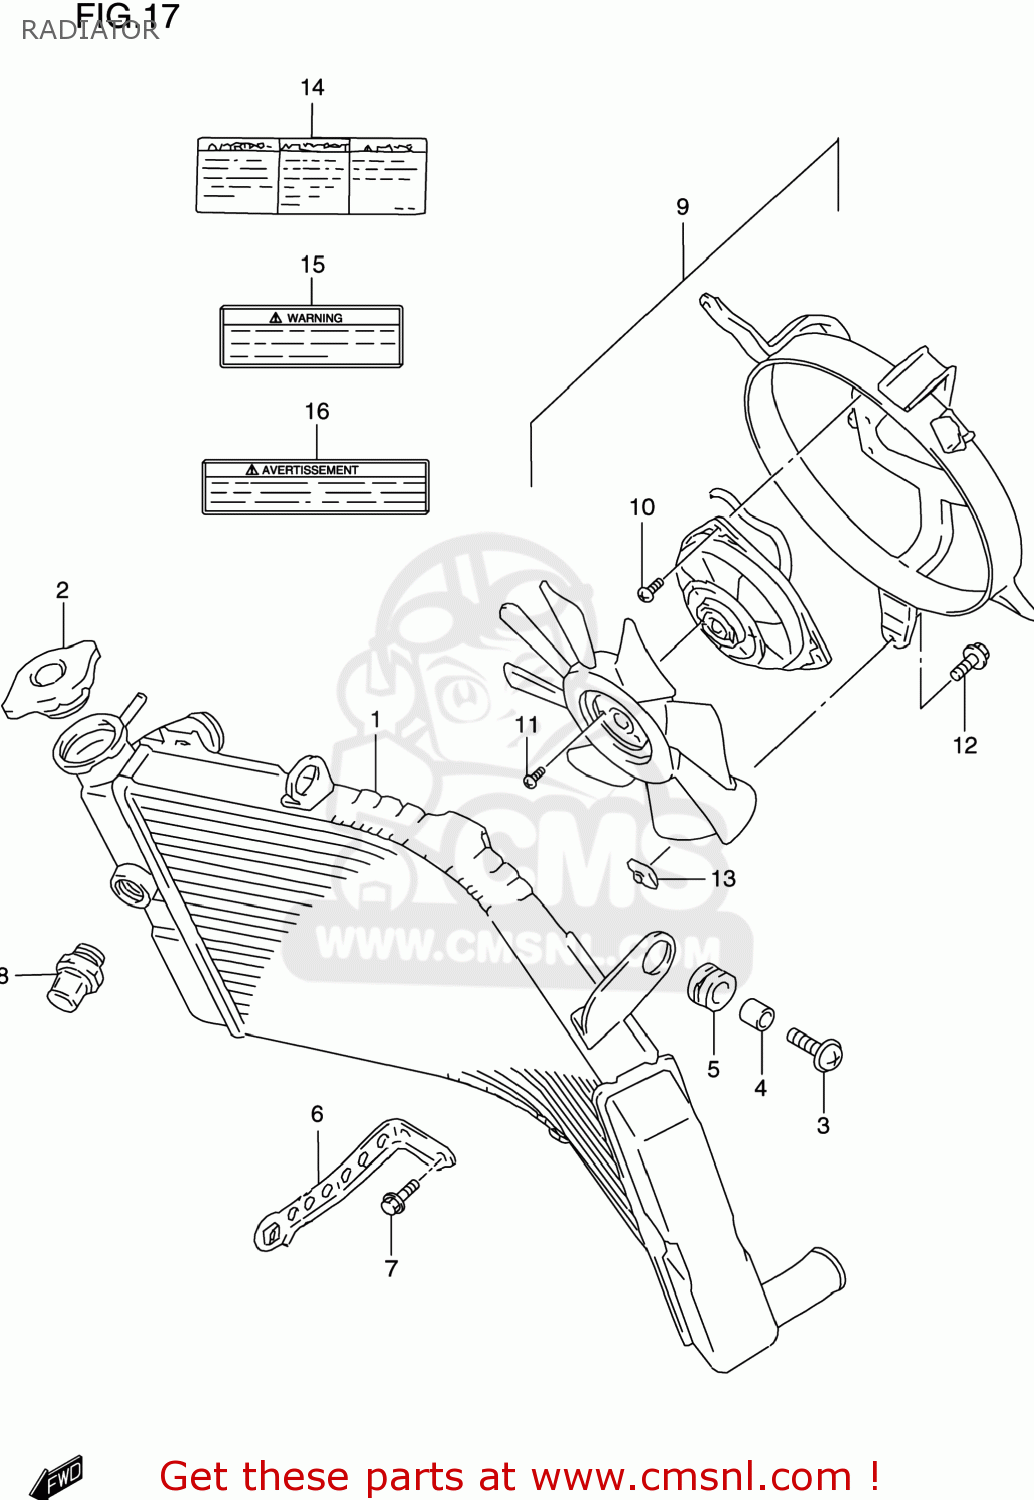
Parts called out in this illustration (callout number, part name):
1	RADIATOR ASSY,WATER
2	CAP,RADIATOR
3	BOLT 6X20
4	SPACER(6.5X10X12)
5	CUSHION
6	BRACKET,RADIATOR LWR
7	BOLT
8	SWITCH,RADIATOR FAN
9	FAN ASSEMBLY,RADIATOR
10	SCREW
11	SCREW 4X6
12	BOLT
13	NUT
14	LABEL, COOLING FAN
15	LABEL (COOLING FAN)
16	LABEL,COOLING FAN
